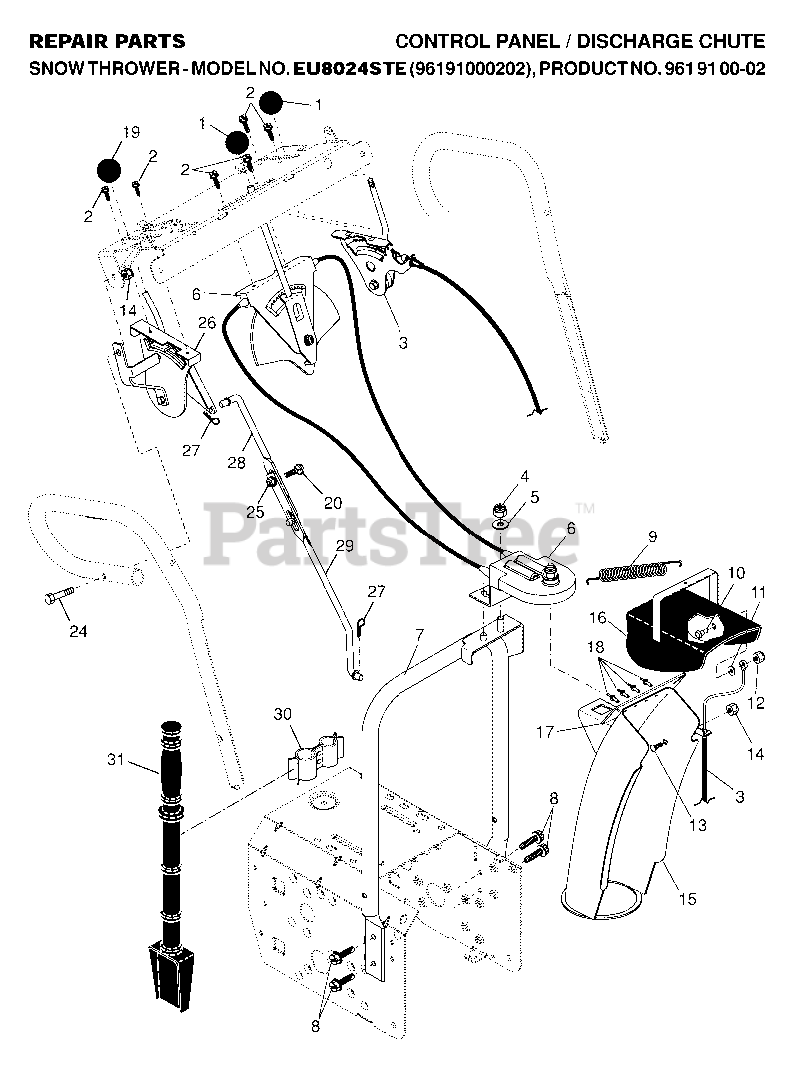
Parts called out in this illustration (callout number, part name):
1	KNOB, LEVER
2	SCREW #10-24 X 5/8
3	CONTROL.CABLE.DEFLECTOR
4	NUT
5	WASHER
6	CONTROL ASSEMBLY,CHUTE ROTATER
7	SUPPORT, PIVOT
8	SELF-TAPPING SCREW 5/16-18X3/4
9	SPRING.DEFLECTOR.REM.CHUTE
10	BOLT, SHOULDER
11	WASHER, NYLON FRICTION
12	LOCKNUT.NYLOC.1/4-20
13	BOLT
14	NUT.LOCK.5/16-18
15	CHUTE ASSEMBLY
16	DEFLECTOR.WELDMENT.PNT.ORANGE
17	SEAL, DEFLECTOR
18	RIVET BLIND
19	RP KNOB, SPEED CONTROL LEVER
20	BOLT
25	NUT, HEX FLANGE 5/16-18
26	HEAD ASSY SPEED
27	SPRING RETAINER
28	ROD, UPPER SPEED CONTROL
29	ROD, LOWER SPEED CONTROL.SNOW
30	CLAMP.ASM.CLEANOUT.TOOL.SNOW
31	CLEAN OUT TOOL
